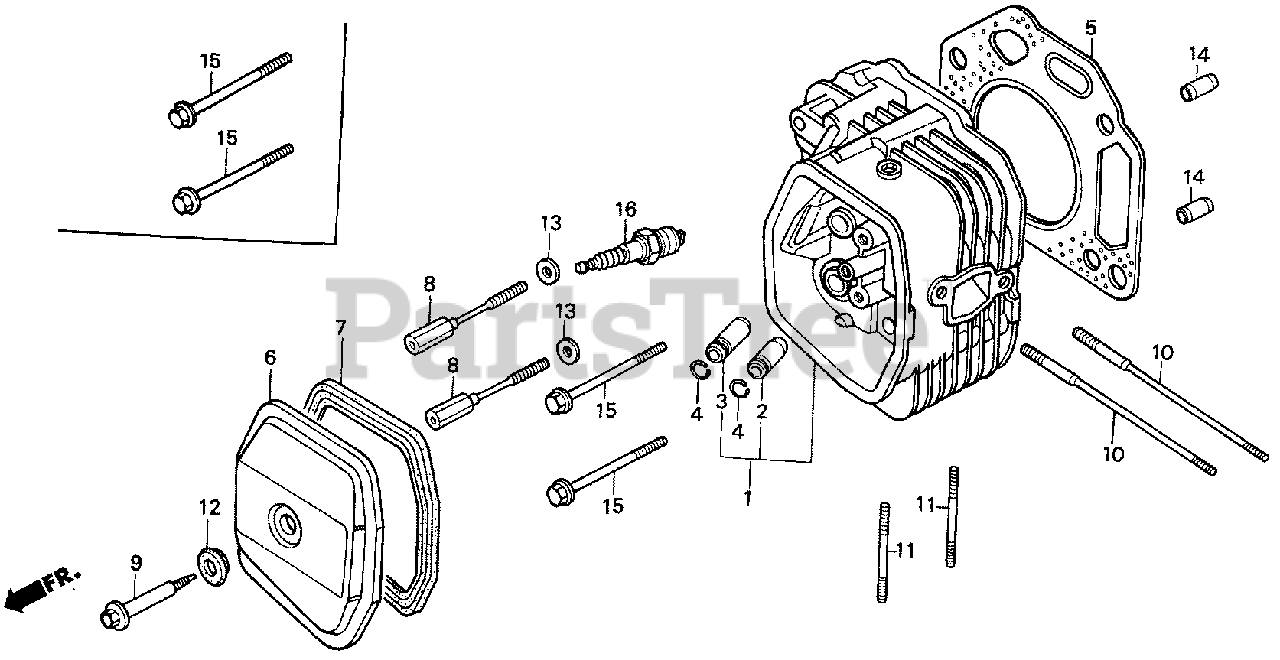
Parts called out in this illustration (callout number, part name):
1	CYLINDER HEAD
2	GUIDE, VALVE (OS)
3	GUIDE, EX. VALVE (OS)
4	CLIP, VALVE GUIDE
5	GASKET, CYLINDER HEAD
6	COVER, HEAD
7	GASKET, CYLINDER HEAD COVER
8	BOLT, SPECIAL HEAD COVER
9	BOLT, HEAD COVER
10	BOLT, STUD (8X131.5)
11	BOLT, STUD
11	BOLT 2, STUD (8X32)
12	WASHER, HEAD COVER
13	WASHER, SPECIAL (11X21X2.3)
14	PIN A, DOWEL (12X20)
15	BOLT, FLANGE (10X80)
16	SPARK PLUG (BPR5ES) (NGK)
16	SPARK PLUG (W16EPR-U) (DENSO)
